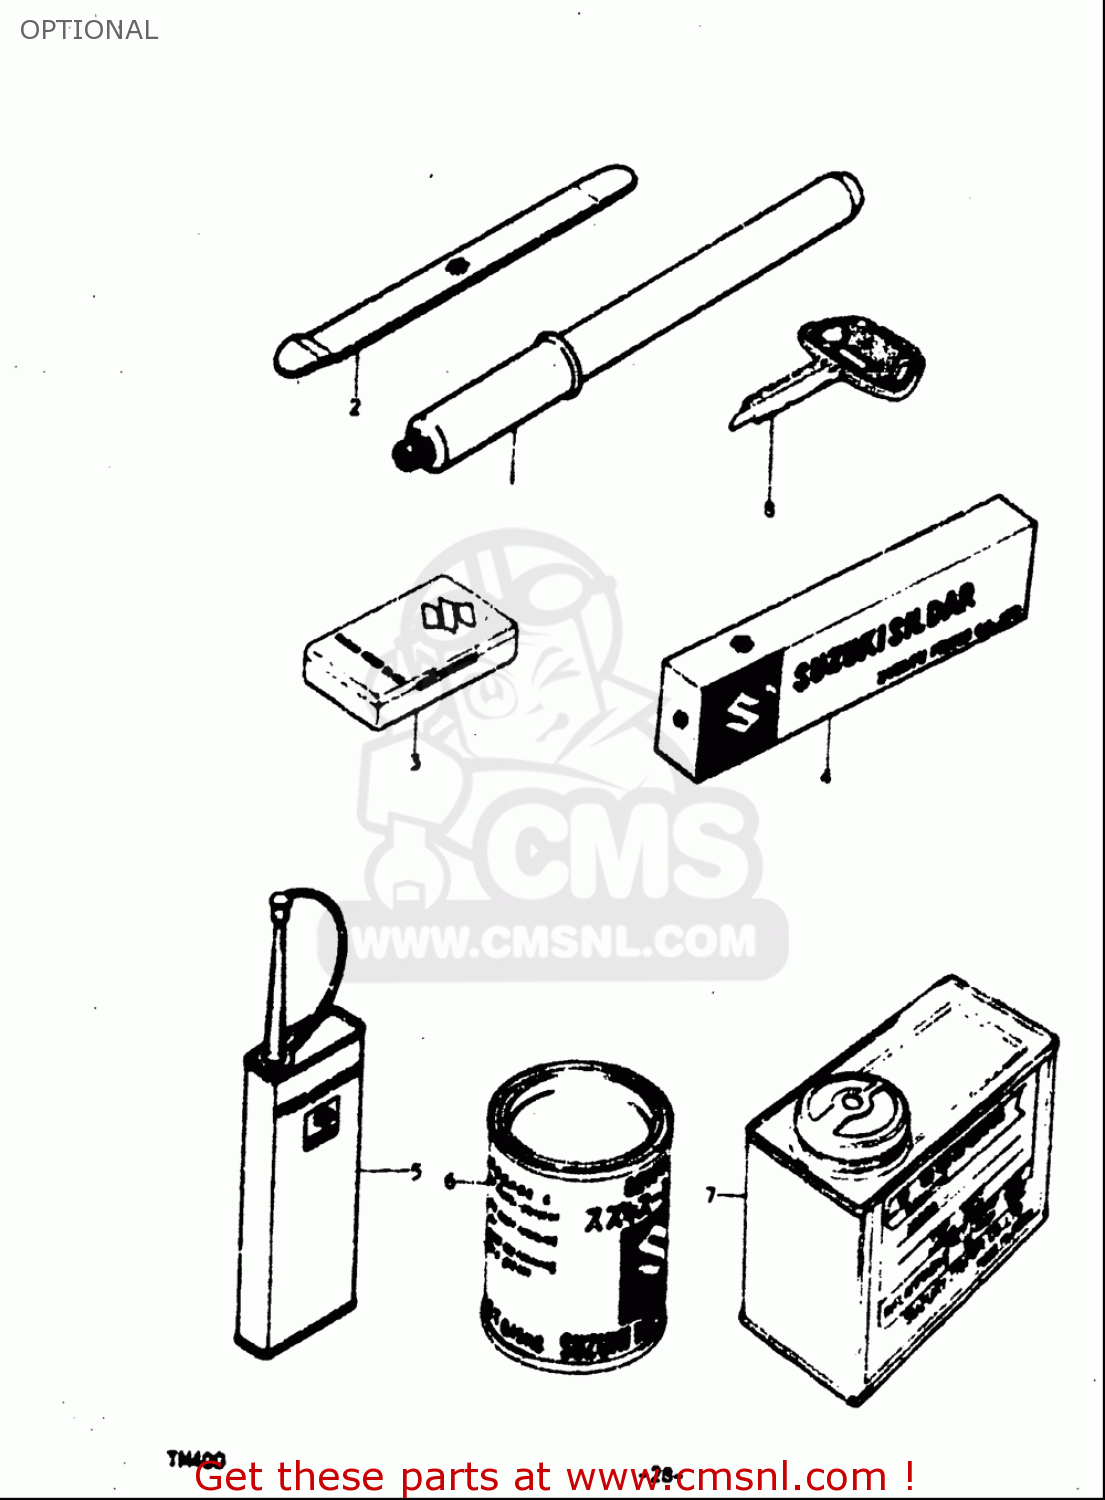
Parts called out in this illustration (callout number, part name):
2	LEVER,TIRE
5	THREAD LOCK NO.1401 CLEAR 200G
6	GREASE(C)EP2 LITHIUM 150G
8	KEY,BLANK
